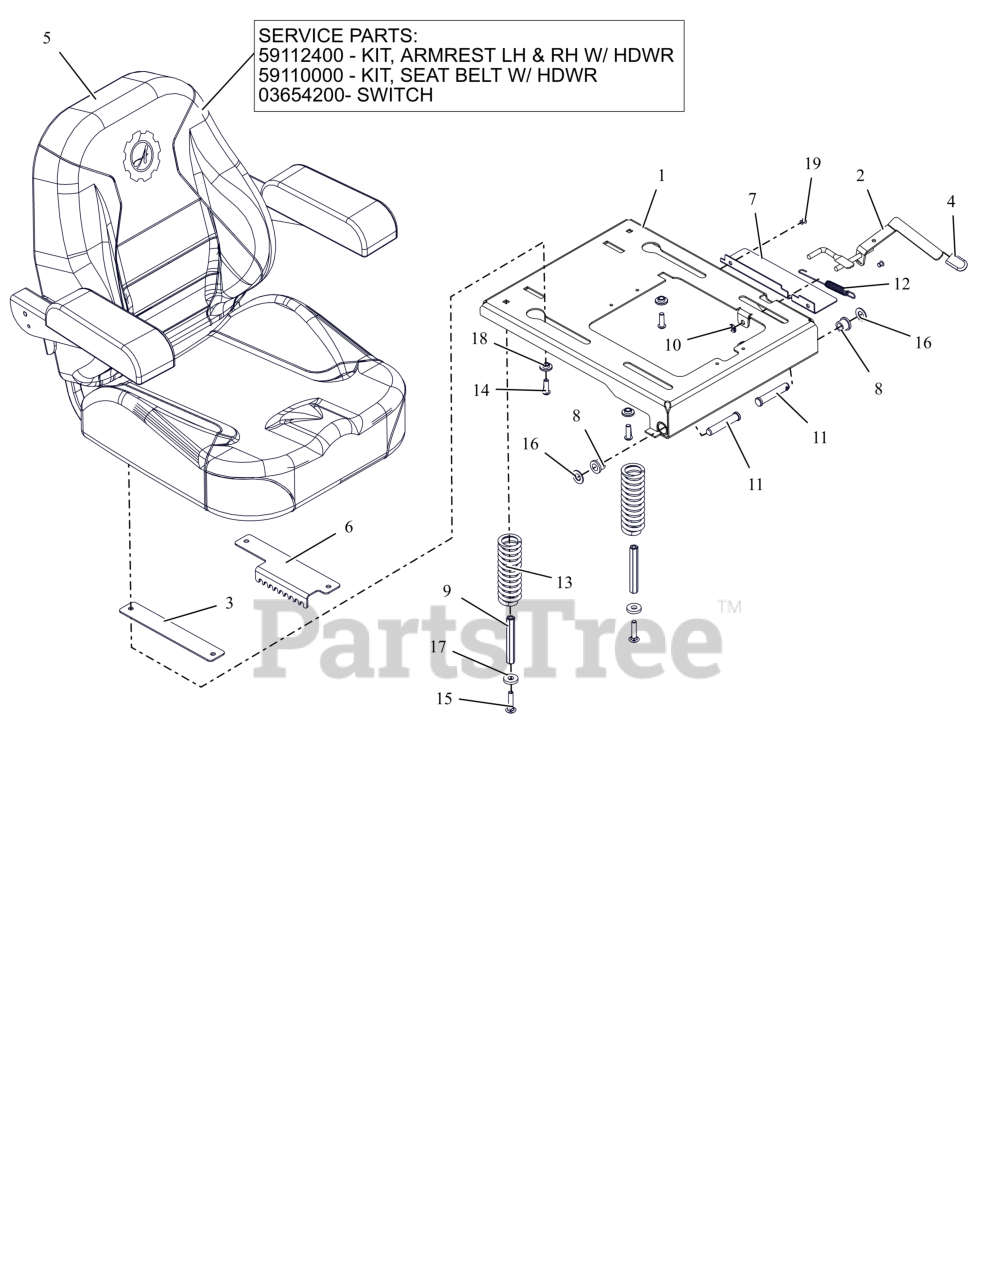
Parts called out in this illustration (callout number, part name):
1	WLDMT, SEAT PLATE HD
2	WLDMT, SEAT SLIDE LEVER
3	PLATE, ADJUSTABLE SEAT SLIDE
4	GRIP, SEAT LEVER, GREY
5	SEAT, APEX
5	KIT-LH & RH ARM REST-05124700
5	KIT-SEAT BELT REPLACE-05007300
5	SWITCH- SEAT
6	PLATE, HD SEAT ADJUSTMENT
7	GUARD, SEAT PLATE
8	BSHG, FLG .516X.750X.625X.937
9	NUT, COUPLING 5/16X18 X 3.75
10	NUT-PUSH .312
11	PIN-CLIC .50X2.70X2.31 -ZCC
12	SG-TENS .06X.482X5.35
13	SPRING, COMPRESSION SEAT 224LB
14	BLT,SHCS-BTN .31-18X1.00 ZCC
15	BLT,RHSN .31-18X1.50 G5 ZCC
16	WSHR, FLT .531X1.00X.063 ZCC
17	WSHR, FLT .406X1.00X.188 ZCC
18	BSHG-FLG .325X.499X.3X.875
19	RIVET, .1875 AL/AL .126-.250
